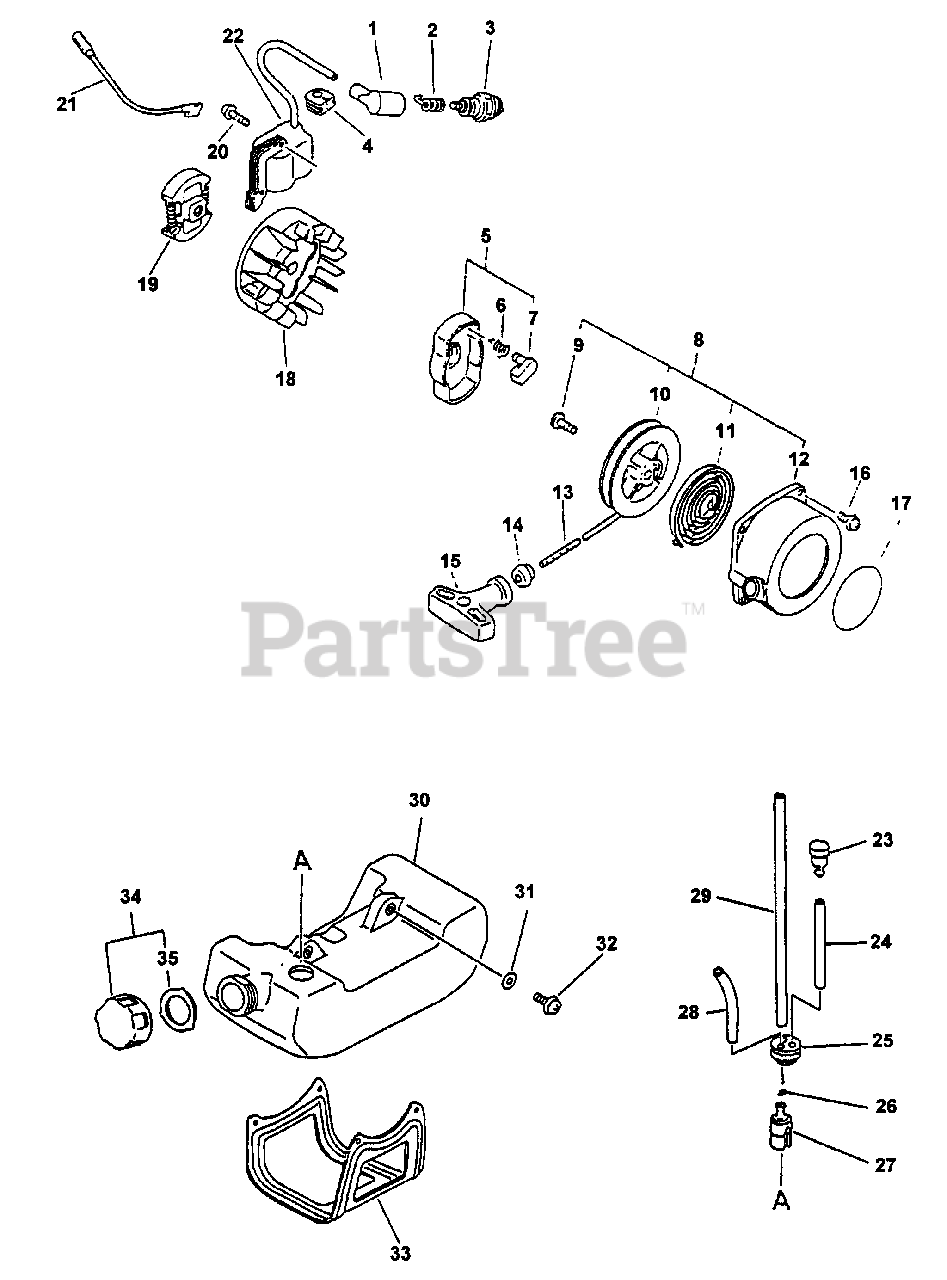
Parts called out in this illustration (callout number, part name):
1	CAP, SPARK PLUG
2	TERMINAL, SPARK PLUG
3	SPARK PLUG - BPM-7Y
5	PAWL ASSY, STARTER
6	SPRING, RETURN
7	PAWL, STARTER - BLACK
8	STARTER ASSY, RECOIL
9	SCREW
10	REEL, ROPE
11	SPRING, RECOIL
12	CASE, RECOIL STARTER
14	GUIDE, ROPE
15	GRIP, STARTER
16	BOLT 4×16
17	LABEL, ECHO
19	CLUTCH ASSY
20	SCREW 4×22
21	LEAD - GROUND
22	COIL, IGNITION
23	VENT ASSY
24	PIPE, FUEL 3x-5x-70 BLACK
25	GROMMET, FUEL
26	CLIP 6 MM
27	FILTER, FUEL
28	PIPE, FUEL RETURN 3×6×90 MM CLEAR
29	PIPE, FUEL 3x-5x-180
30	TANK, FUEL
31	WASHER 5.5×12×0.8
32	SCREW 5×16
33	GUARD, FUEL TANK
34	CAP ASSY, FUEL
35	GASKET, FUEL CAP
